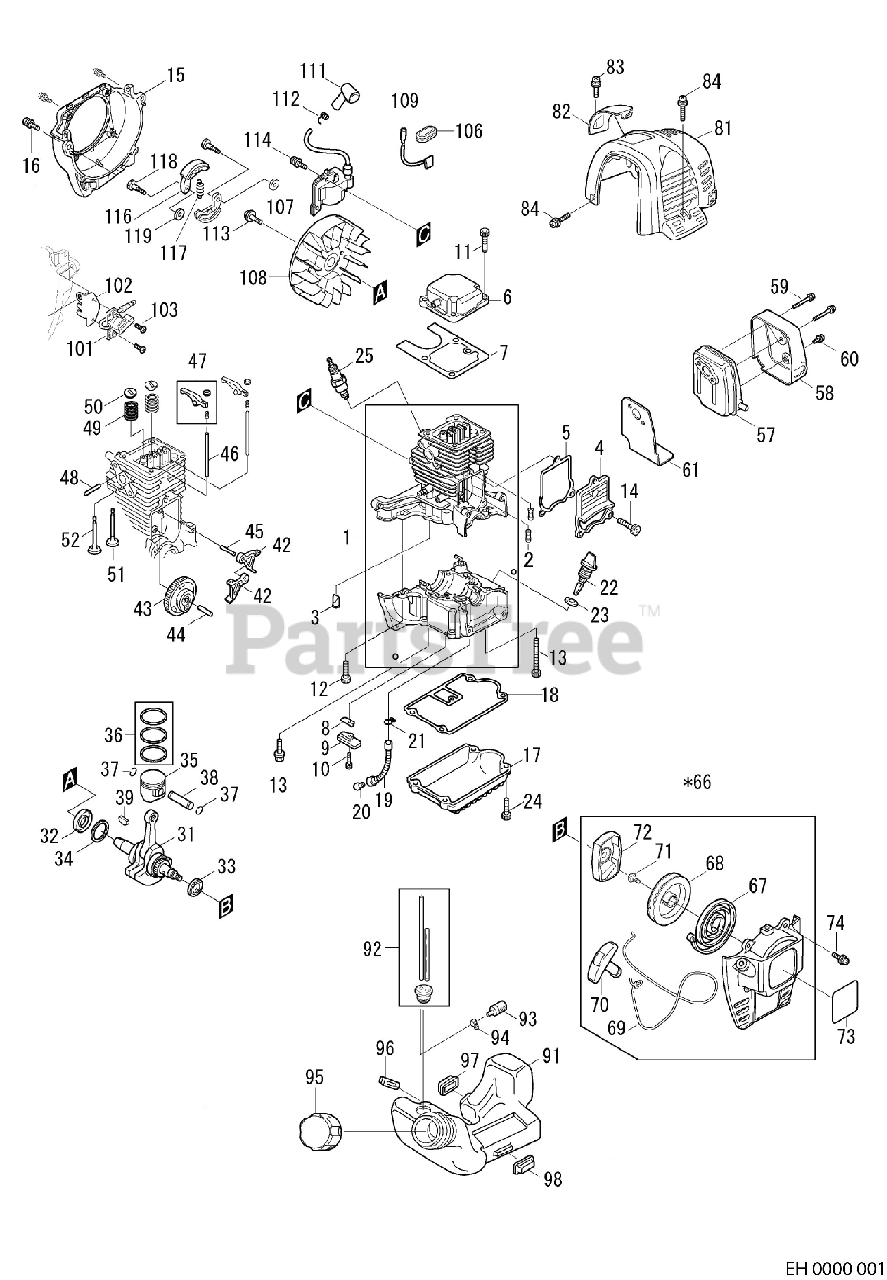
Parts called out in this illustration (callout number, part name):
1	CYLINDER BLOCK SET
4	COVER, CAM GEAR
5	GASKET, COVER CAM GEAR
6	ROCKER COVER CP
7	GASKET, ROCKER COVER
9	RETAINER PLATE
10	BOLT - SOCKET HEAD
11	BOLT - SOCKET HEAD
12	BOLT - SOCKET HEAD
13	BOLT - SOCKET HEAD
14	BOLT - SOCKET HEAD
15	HOUSING, BLOWER
16	BOLT - SOCKET HEAD
21	HOSE CLAMP
24	BOLT - SOCKET HEAD
25	PLUG, SPARK
32	SEAL, OIL - (L)
33	SEAL, OIL - (S)
36	PISTON RING SET
39	KEY - WOODRUFF
42	LIFTER, CAM
44	SHAFT, CAM GEAR
45	SHAFT, CAM LIFTER
47	ROCKER ARM ASSY
50	RETAINER, SPRING
51	VALVE, EXHAUST
57	MUFFLER, EXHAUST
58	COVER, MUFFLER
59	BOLT - SOCKET HEAD
60	SCREW
61	GASKET, MUFFLER
66	STARTER COVER ASSY
67	SPRING, RETURN
73	LABEL, MODEL - ROBIN/SUBARU
74	SCREW ASSY
81	COVER, CYLINDER - YELLOW
83	SCREW
84	SCREW ASSY
95	FUEL TANK CAP ASSY
103	SCREW - PAN HEAD
107	COIL, IGNITION
112	TERMINAL, PLUG CAP
113	BOLT ASSY
114	BOLT - SOCKET HEAD
117	CLUTCH ASSY
